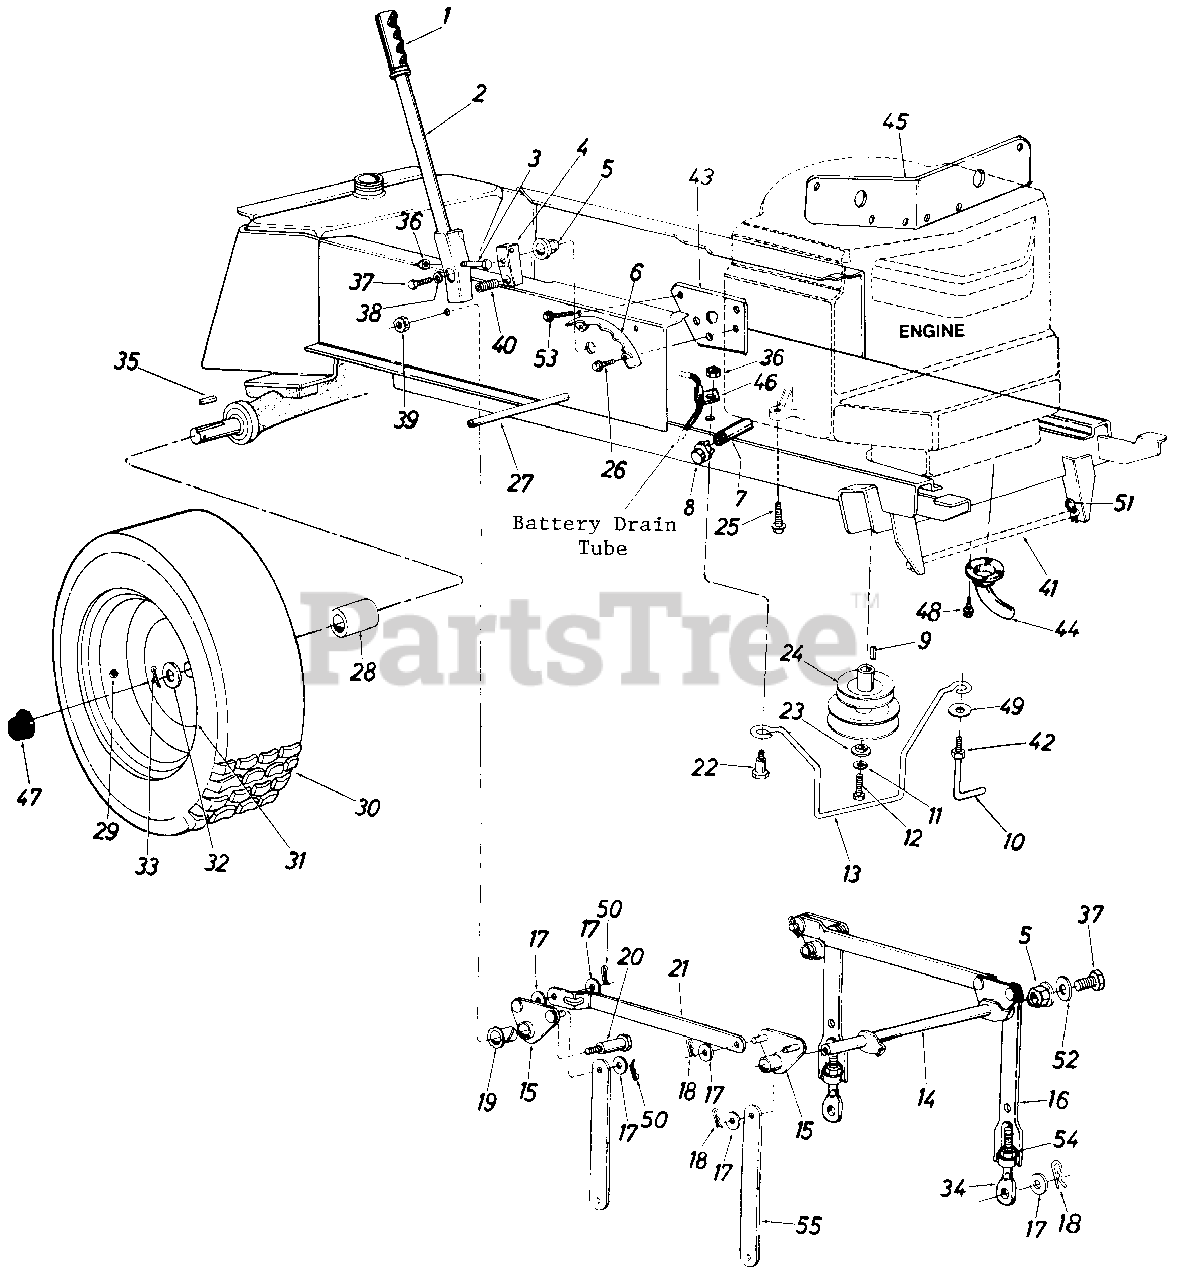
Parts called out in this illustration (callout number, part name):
2	Lift Handle Ass'y.
3	Hex Bolt 5/16-18 x 1.5" Lg.
4	Lift Shaft Drive
5	Plastic Hex Brg. 5/8" I.D.
6	Index Brkt. Deck Lift
7	Pipe Nipple 3/8-18 Npt.
8	Pipe Cap 3/8-18 Npt.
9	Sq. Key 1/4" x 1/4" x 1.50" Lg.
10	Belt Guard Lock Pin
11	L-Wash. 7/16" I.D.
12	Hex Scr. 7/16-20 x 1.50" Lg.
13	Belt Guard
14	Lift Shaft Ass'y.
15	Lift Pivot Brkt. Ass'y.
16	Adj. Deck Lift Link
17	Fl-Wash. 1/2" I.D. x 1.00" O.D. x .090
18	Hairpin Cotter
19	Nyliner 5/8" I.D. x .88" Lg.
20	Shld. Bolt 5/8" Dia. x .96" Lg. 3/8-16
21	Connecting Link
22	Shld. Bolt .437 Dia. x .268 0 Lg. 5/16-18
23	Flat Wash. .44" I.D. x 1.25" O.D. x .17
24	Two-Step Engine Pulley 4.75" & 5.56
25	Hex Wash. Hd. Scr. 3/8-16 x 1.25" Lg.
26	Hex Thd. Rolling Scr. 5/16-24 0 x.50" Lg.
27	Running Board Rod
28	Spacer 1.0" I.D. x 1.25" O.D. x 2.12" Lg.
29	Air Valve
33	Cotter Pin 3/16" Dia. x 1.50" Lg.
34	Eye Bolt Adj. Link 1/2-13 Thd.
35	Sq. Key 1/4 x 3.0"
36	Hex Cent. L-Nut 5/16-18 Thd.
37	Hex Scr. 5/16-24 x .62" Lg.
38	L-Wash. 5/16" I.D.
39	Hex Top L-Nut 3/8-16 Thd.
40	Compression Spring
41	Deck Connecting Rod
42	Hex Nut 5/16-24 Thd.
43	Index Brkt. Reinforcement Plate
44	Exhaust Pipe
45	Heat Shield
46	Mounting Clamp
47	Hub Cap
48	Hex Wash. Hd. AB-Tap Scr. #10 x .60n Lg.
49	Bell-Wash. .39" I.D.
50	Cotter Pin .09 Dia. x 1.0" Lg.
51	Int. Cotter Pin
52	Flat Wash. .34" I.D. x 1.12" O.D. x .125
53	Hex Wash. Hd. AB-Tap Scr. 5/16 x .62" Lg.
54	Hex Nut l/2-13 Thd.
55	Deck Link
